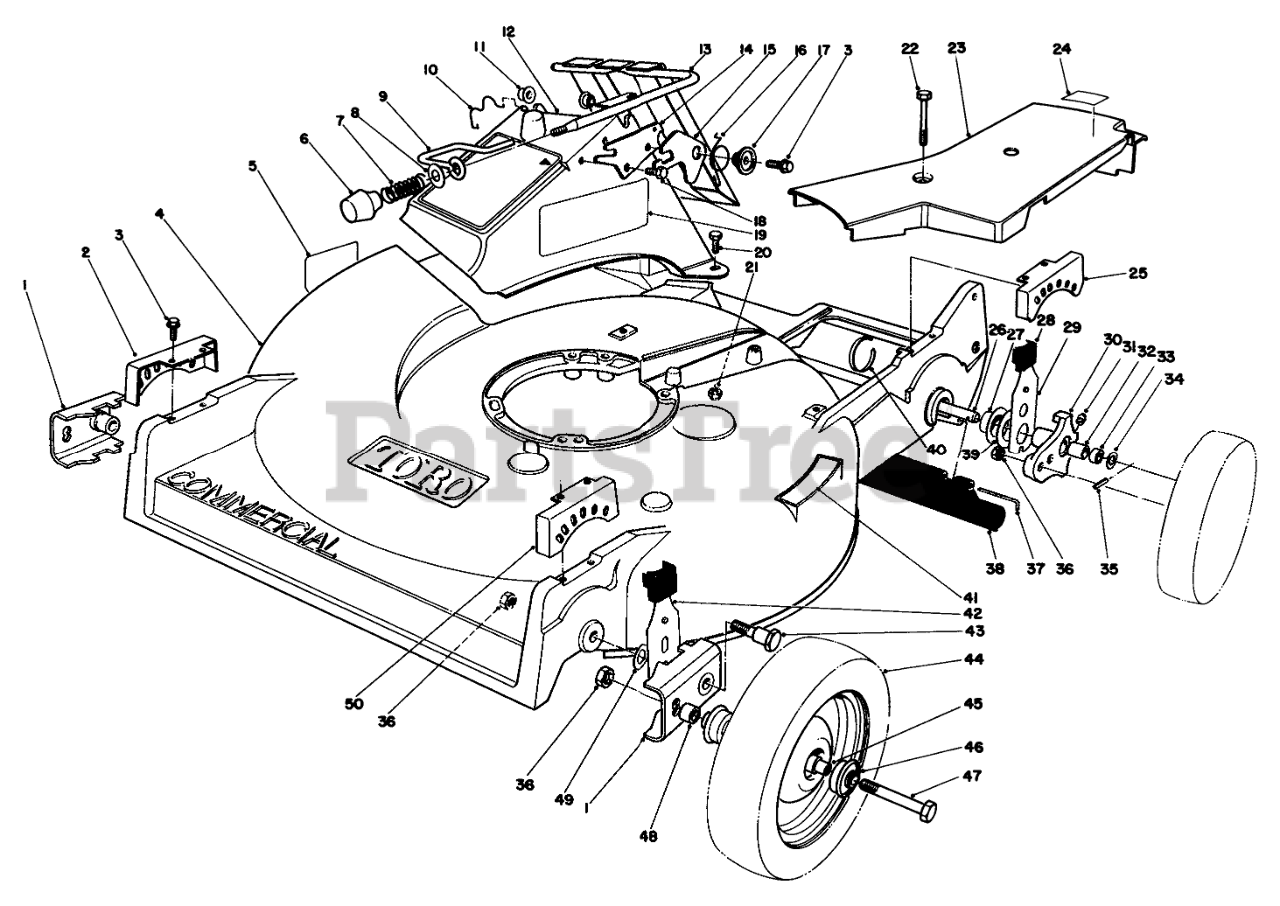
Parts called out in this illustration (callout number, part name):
1	PIVOT ARM
2	QUADRANT-FRONT, RH
3	Screw
4	Housing-Commercial (Incl. Ref. #5, 41)
5	DECAL-DANGER
7	COMPRESSION SPRING
8	WASHER-FLAT
9	DOOR LATCH
10	DOOR RETAINER
11	BUSHING-NYLON
12	Chute & Door Assy. (Incl. Ref. #3, 6-11 & 13-21)
13	DOOR & HANDLE WA
14	DOOR LATCH PLATE
15	SAFETY LATCH
16	TORSION SPRING
17	DOOR SPACER
18	SCREW-HWH
19	DECAL SAF INST
20	SCREW-HH
21	NUT-LOCK, NI
22	SCREW-HHFTF
23	Belt-Cover
24	Label-Grease
25	QUADRANT-REAR, LH
26	SHAFT-AXLE, REAR
27	CAP-END
28	KNOB-ARM
29	Spring Arm
30	Pivot Arm (Incl. Ref. #31-33)
31	FITTING-GREASE
32	BUSHING
33	BUSHING
34	WASHER-PLAIN
35	PIN-SPIROL
36	NUT-LOCK, NI
37	ROD-SHIELD
38	SHIELD-TRAILING
39	WASHER
40	TIE-CABLE
41	STEP PAD DECAL
42	SPRING ARM ASM-FRONT
43	PIVOT SCREW
44	Wheel & Tire Assembly (Incl. Ref. #45 & 46)
45	SPACER-BEARING
46	BEARING-WHEEL
47	SCREW-HH
48	SPACER-WHEEL
49	WASHER-PIVOT
50	QUADRANT-FRONT, LH
